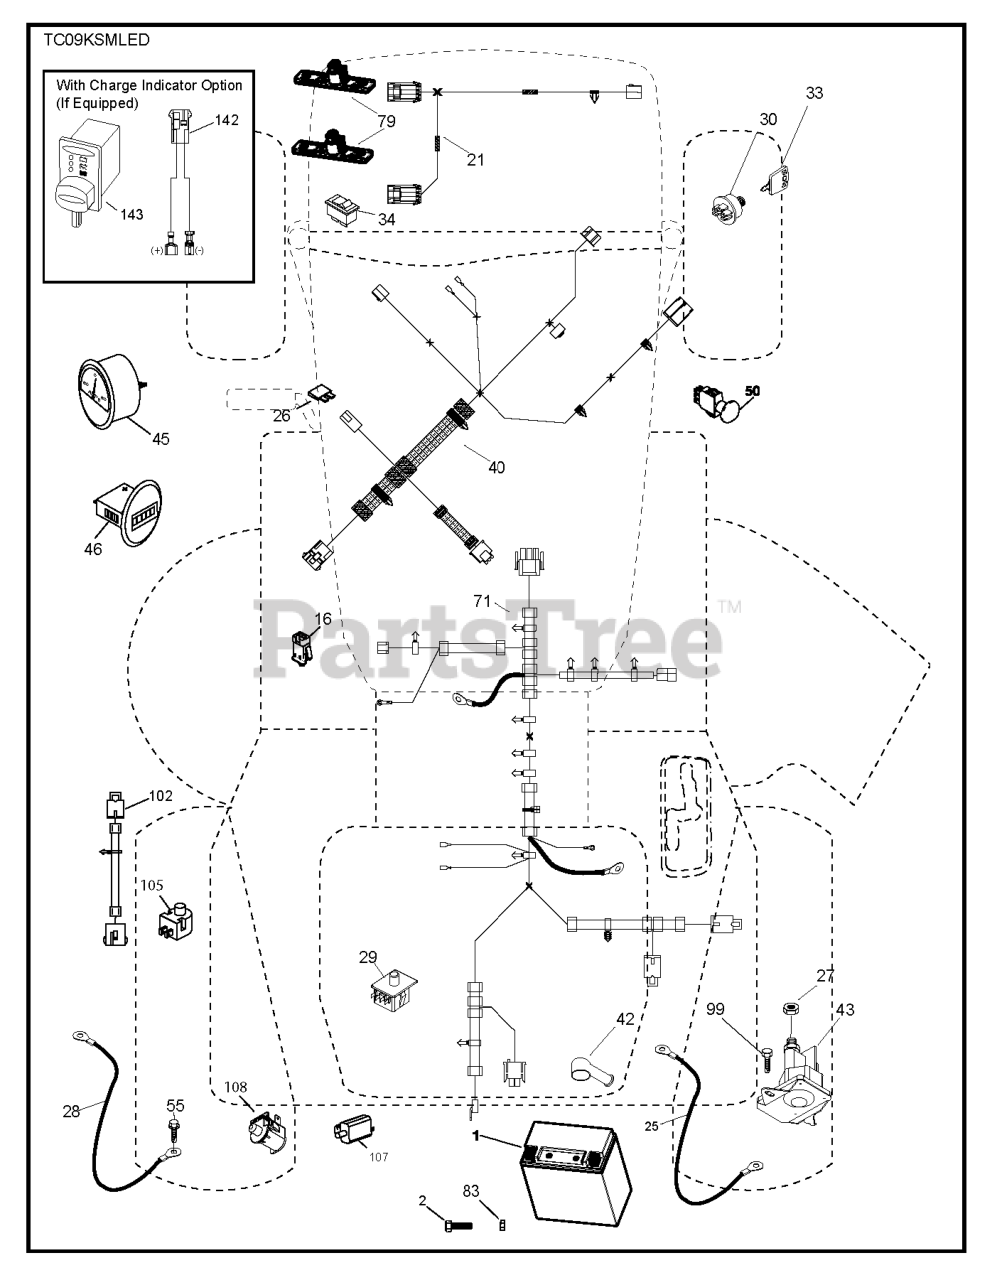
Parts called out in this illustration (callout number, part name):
1	BATTERY BATTERY 14AH 12V LEOC
16	SWITCH INTERLOOK PUSH-IN
25	CABLE.BATT.8GA.RED9.CRD2.5
26	FUSE 20AMP
28	CABLE.BATT.BLCK10.SLV.CRD2.5
29	SWITCH.SEAT.DP W/RAMPS
30	SWITCH.IGN.DELTA.W.LGH.ROS
33	KEY.CHAIN.BLISTER.PACK.GEN.USA
33	KEY.CHAIN.BLISTER.PACK.GEN.INT
40	HARNESS.DASH.TCRD.EL.RND.CH.RS
42	TERMINAL COVER
50	RP SWITCH.PTO.TERMINAL.STD.RED
55	SCREW 5/16"
71	HARNESS
83	NUT SQUARE M6, 11X8.5 ZPB
99	SCREW
102	HARNESS ASSY
105	REVERSE SWITCH
107	.WITCH.FULL BAGGER.INDICATOR
108	SWITCH.SNPMT.NCBT.CRD.MTL.BKPL
